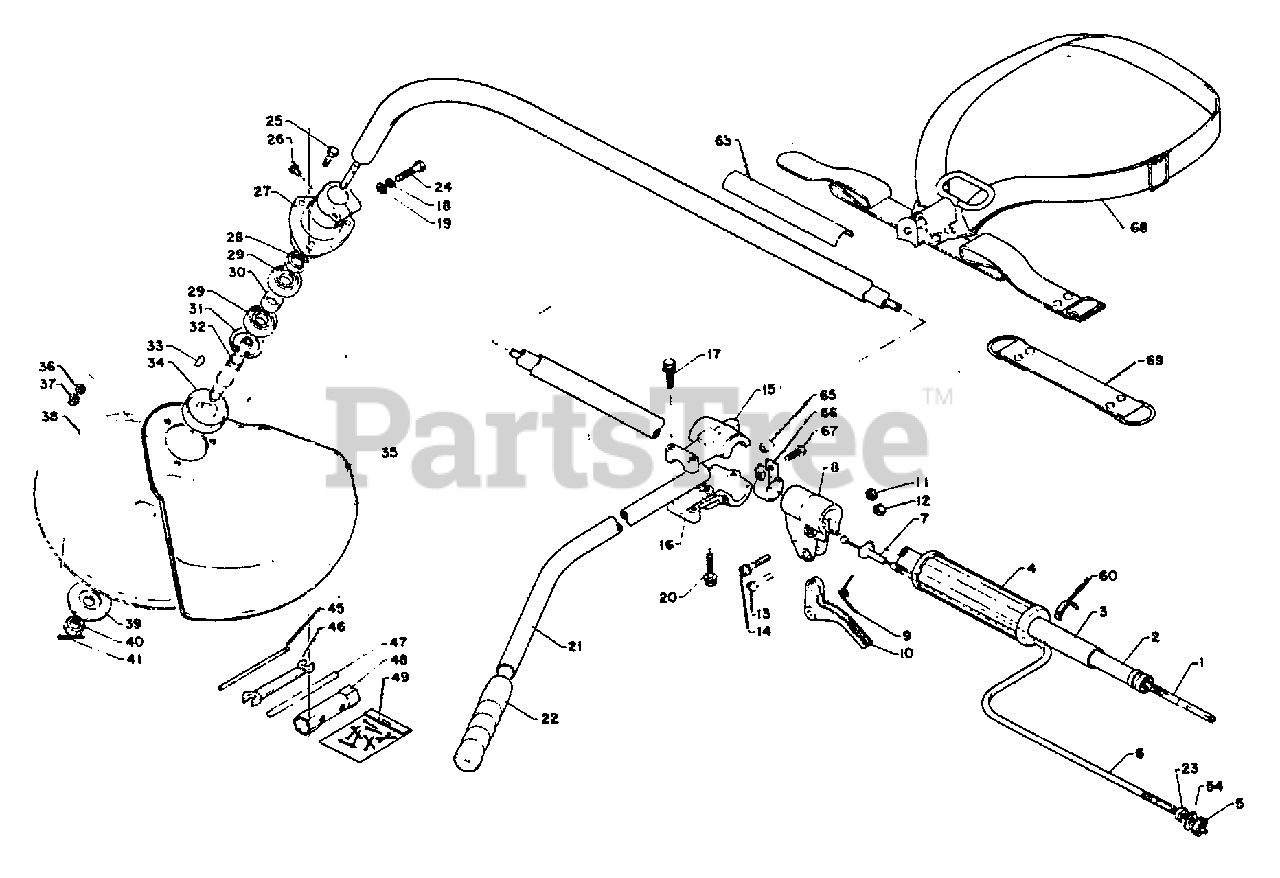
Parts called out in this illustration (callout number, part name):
1	DRIVESHAFT
2	BUSHING
3	PIPE, MAIN
6	CABLE, THROTTLE
7	GUIDE, CABLE
8	BRACKET, TRIGGER
9	SPRING, TRIGGER
10	TRIGGER, THROTTLE
12	LOCKNUT - 5
13	SCREW - 5X30
14	SCREW - 5X28
15	BRACKET, HANDLE
16	BRACKET, HANDLE
17	BOLT - 5X25
18	LOCKWASHER - 5
19	WASHER - 5
20	BOLT - 5X28
21	HANDLE - LEFT
22	GRIP, HANDLE
24	BOLT - 5X25
25	SCREW - 4X18
26	SCREW - 4X10
27	CASE, GEAR
28	NUT - 12
29	BEARING, BALL - 6001
31	RING, RETAINING - 28
32	DRIVESHAFT
34	ADAPTOR, BLADE - UPPER
35	SHIELD, DEBRIS
36	LOCKWASHER - 4
39	ADAPTOR, BLADE - LOWER
40	NUT - 10 -- LEFT HAND
45	LOCKING TOOL
46	SPANNER - 8X10mm
47	ROD, HANDLE
48	SOCKET WRENCH - 17X19mm
49	PIN, SPLIT - 2X22
54	WASHER - 6
66	HANGER
67	BOLT - 5X14
68	SHOULDER STRAP ASSY
69	STRAP
